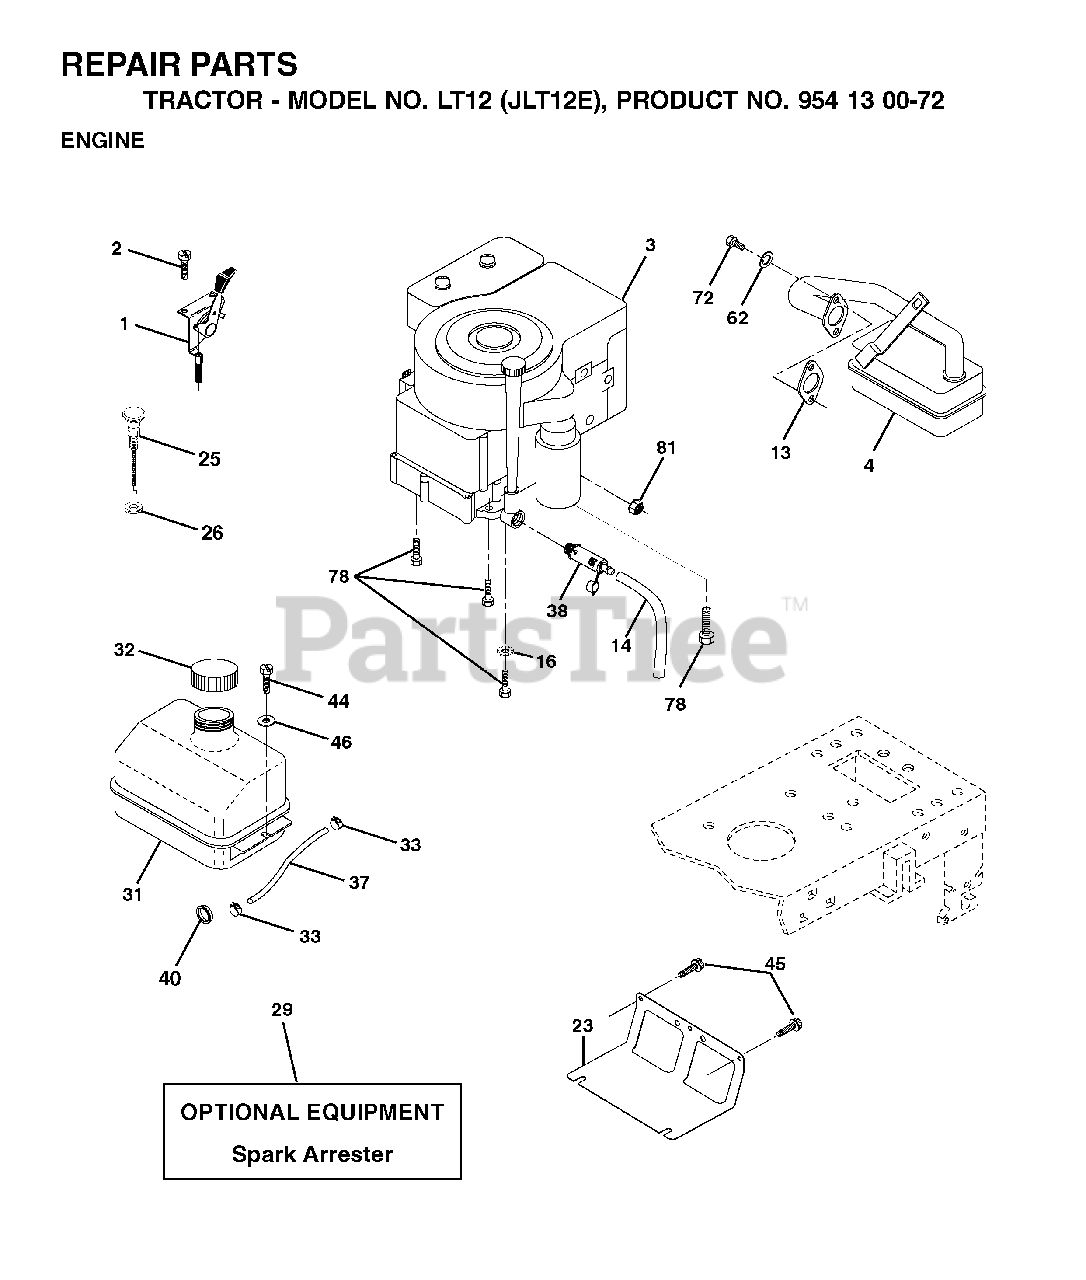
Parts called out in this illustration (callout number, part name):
1	CONTROL TH/CH FLAG
2	SCREW
13	REPL BY 532 27 22-93
14	TUBE, DRAIN OIL ASM.
16	LOCKWASHER
23	SHEILD.BROWNING.DBR.GUARD
26	NUT KEPS 3/8 - 24 UNF
29	ARRESTER SPARK (OPTIONAL)
32	FUEL CAP
33	HOSE CLAMP
37	LINE.FUEL.20
38	PLUG, OIL DRAIN EASY
40	GROMMET T
44	SCREW HEXWSHR 1/4-20X3/4
45	SCREW, 3/8-16X3/4
62	LOCKWASHER
72	SCREW
78	SCREW.3/8-16
81	NUT
